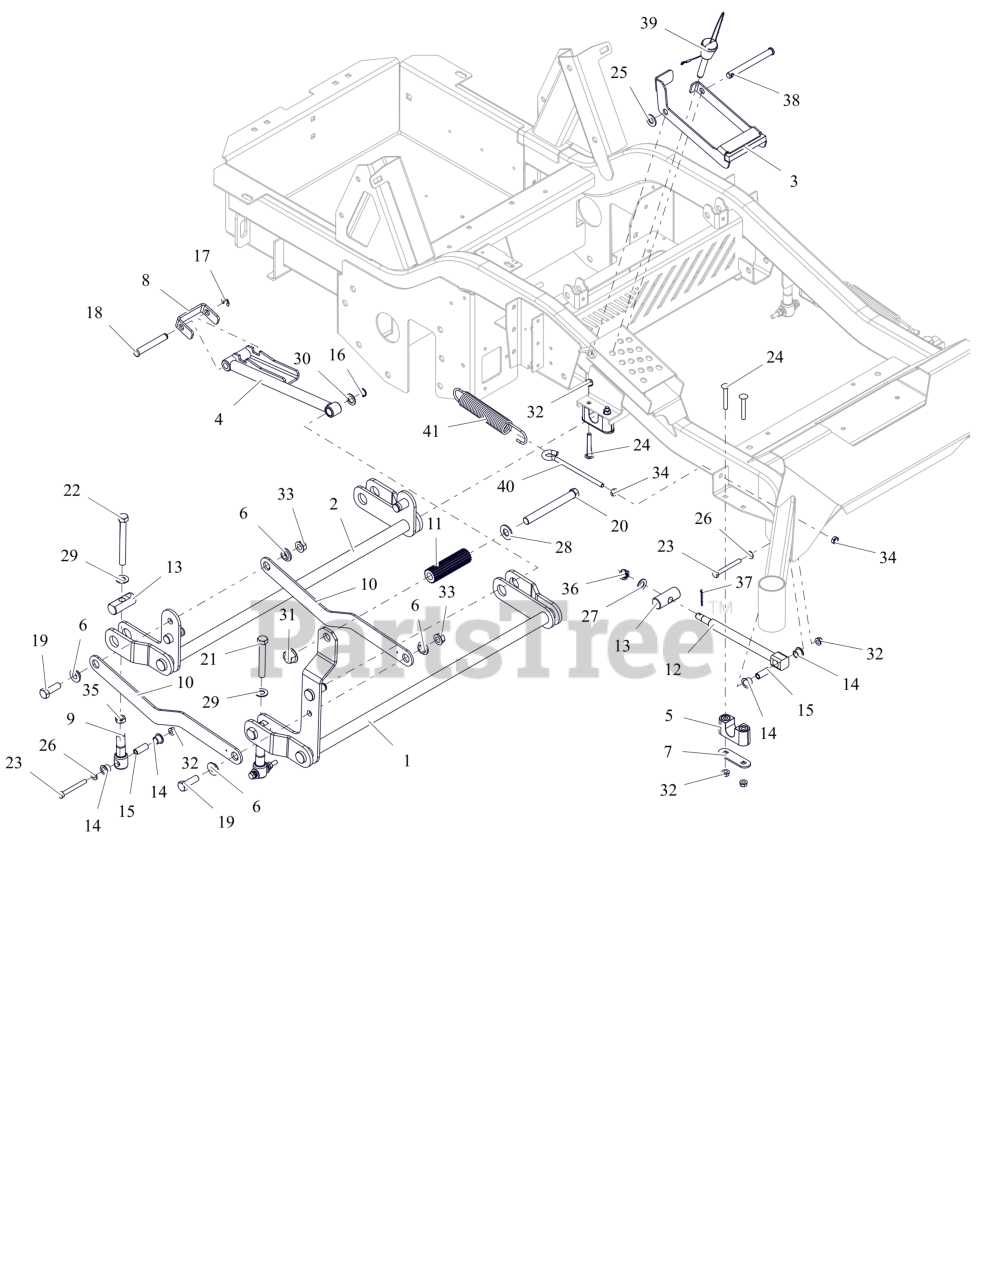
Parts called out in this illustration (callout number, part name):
1	WLDMT, FRONT DECK LIFT PIVOT
2	WLDMT, REAR DECK LIFT PIVOT
3	BRKT, HOC TRANSFER LOCK
4	WLDMT, HOC ARM
5	ASM-BUSHING, DECK LIFT
6	BSHG-FLG .515X.750X.395X1.120
7	PLATE, BEARING SUPPORT
8	BRKT, HOC LINE
9	LINK, DECK LIFT FORMED
10	LINK, DECK LIFT
11	ROD, FOOT PEDAL (BLACK)
12	DRAG,LINK-HD
13	PIN, DECK LIFT
14	BSHG, FLANGED .50X.625X.50X.062
15	SPCR, .31X.50X1.265
16	RG-RTNG-EXT .625X.050
17	RG-RTNG-EXT .500X.042 (E)
18	PIN, .499/.494 x 3.385 CLEVIS
19	BLT,HEX .50-13X1.50 G5 ZCC
20	BLT, HEX .62-11X5.50 G5 FBP
21	BLT, HEX .50-13X3.50F G5 ZCC
22	BLT, HEX .50-13X4.50F G8 ZCC
23	BLT, HEX .31-18X2.75 G5 ZCC
24	BLT, RHSSN.31-18X2.25 G5 ZCC
25	WSHR,FLT .531X1.062X.095 ZCC
26	WSHR,FLT .344X.688X.065 ZCC
27	WSHR, BLVL .531 X 1.000 X .062 MZ
28	WSHRFLT 5/8SAE CARBHARD FBP
29	WSHR, FLT .557X1.040X.102 ZCC
30	WSHR, FLT .630X1.005X.062 ZCC
31	NUT,FLG-TOP LK .625-11 FBP
32	NUT,LK-CTR-FLG .31-18 GF ZCC
33	NUT-LK-TOP-FLG .500-13 GF ZCC
34	NUT-JAM .375-16 G2 ZCC
35	NUT-JAM .500-13 G2 ZCC
36	NUT-SL .50-13
37	PIN,CTR.12X1.25EXTPRSQCT ZC120
38	PIN-SLIC .50X4.97X4.55 -ZCC
39	PIN, MAGNETIC .50X2.50
40	BOLT,.38-16 X 5.25-.62 DIA EYE
41	SG-TENS .162X1.25X8.25 WLD 25
